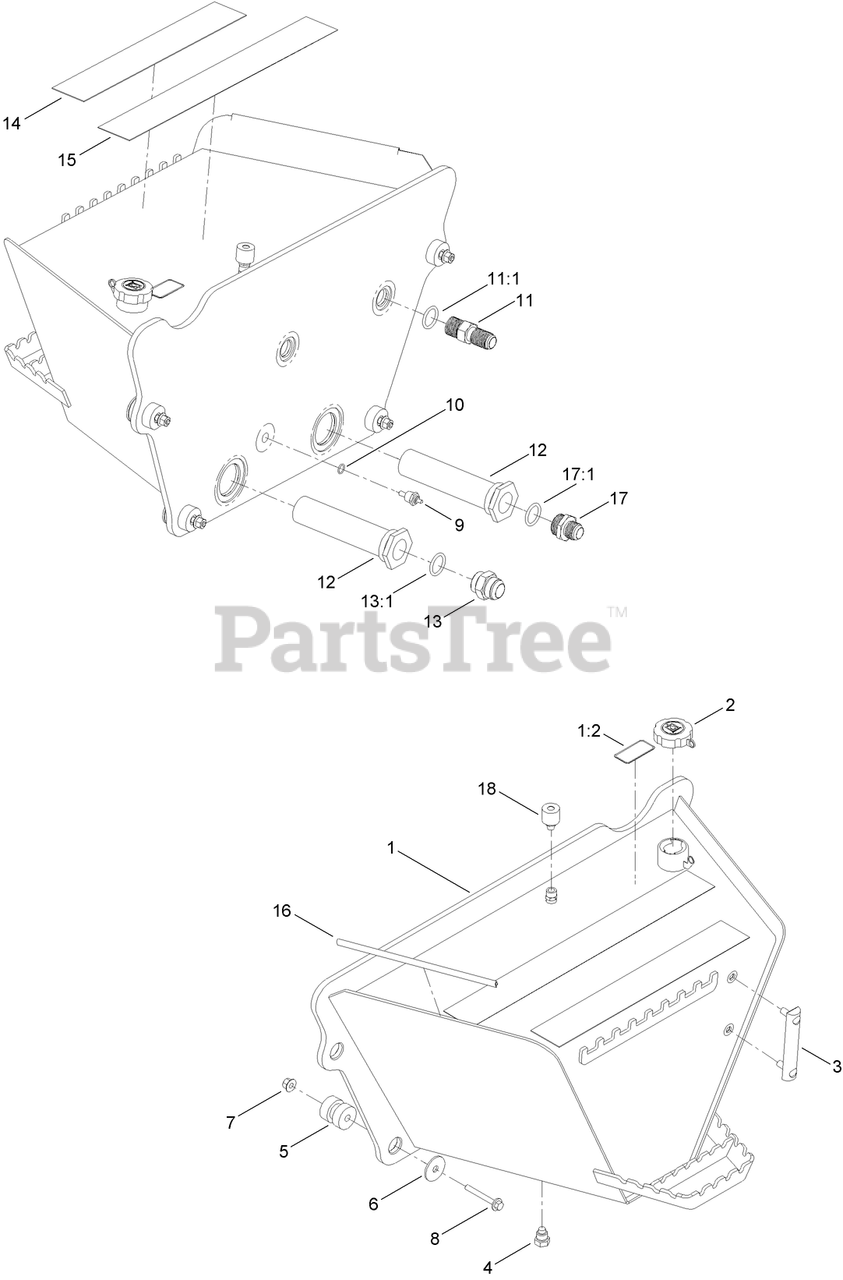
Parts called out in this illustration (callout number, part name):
1	HYD TANK AND DECAL ASM
1:2	DECAL-HYD FLUID
2	CAP-HYD FLUID (W/ LOCK)
3	GAUGE-LEVEL, FLUID (W/THERMOMETER)
4	PLUG-HEX, MAGNETIC
5	ISOLATOR-MOUNTING, UNIVERSAL
6	WASHER-FLAT
7	NUT-LOCK, HHF
8	SCREW-HHF
9	SENSOR-SENDER, OIL/WATER TEMP
11:1	O-RING
12	STRAINER-MOUNTED, TANK
13	FITTING-STRAIGHT
13:1	O-RING
14	TAPE-ANTI SKID, LOWER STEP
15	STRIP-ANTI SKID
16	STRIP-SEAL
17	ADAPTER-STRAIGHT
17:1	O-RING
18	BREATHER
